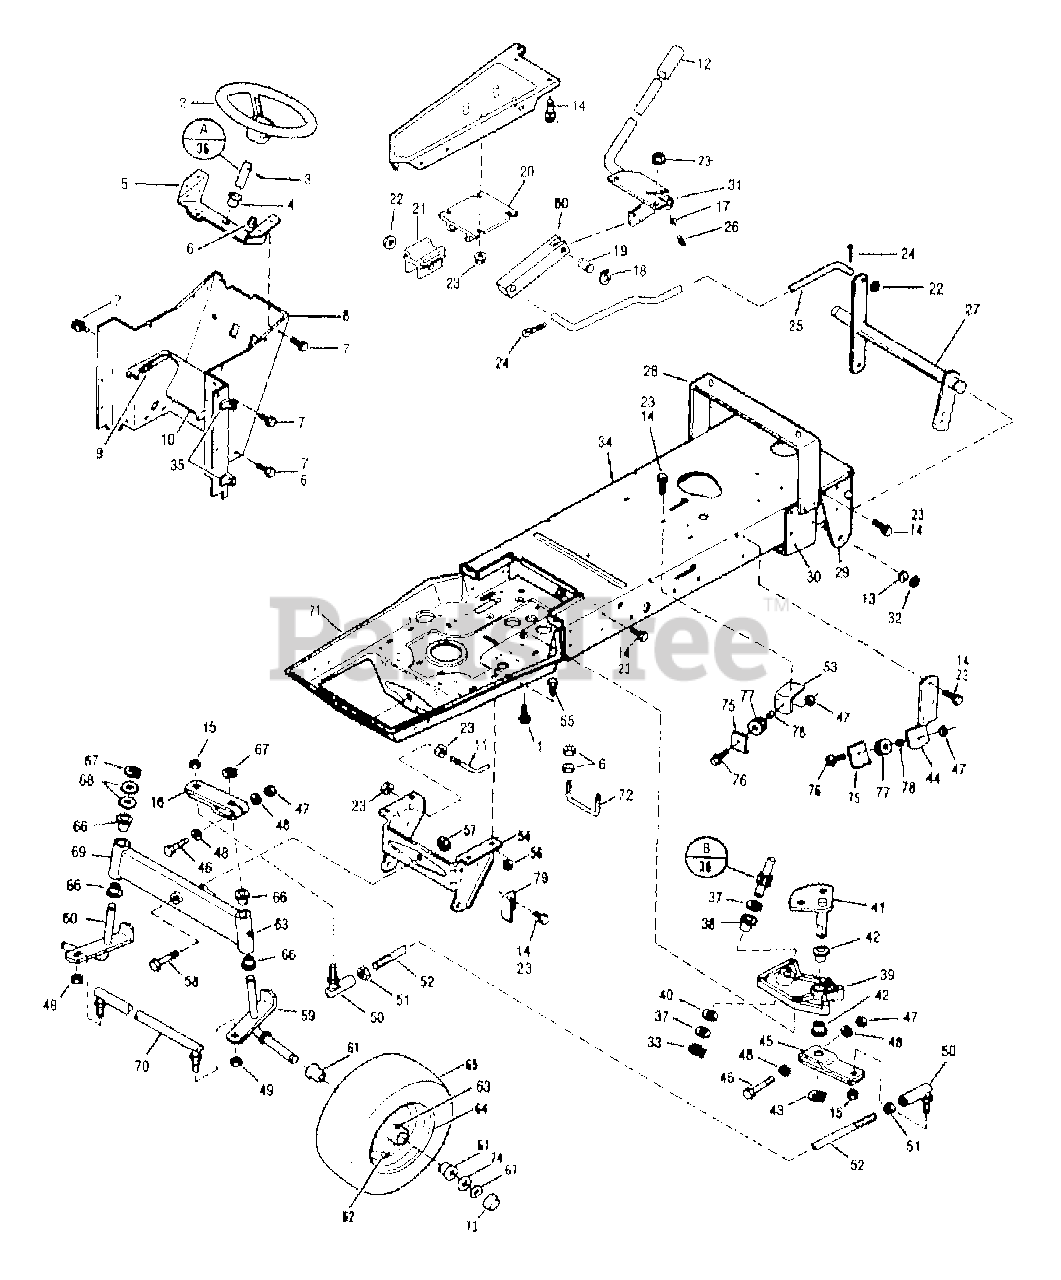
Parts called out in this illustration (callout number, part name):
1	SCR-HFLK 5/16-18X.75
2	WHEEL-STEERING
4	BEARING-FLANGED NYLON
5	SUPPORT-STEERING SHAFT
6	NUT-HF/LK 1/4-20 ZP
7	SCR-HH 1/4-20X.625 {7}
8	SUPT-INSTRUMENT PANEL
9	NUT-SPEED
10	SUPPORT-BATTERY
11	GUIDE-BELT
12	GRIP-FLEX
13	WASHER-1.38 X.765X .06 ZP
14	SCR-LOCK
15	NUT-HEX/JAM 1/2-20 ZP
16	ARM-STEERING
17	WASHER
18	RING-RETAINING
20	KIT-GUIDE (TRACTOR)
21	KIT-GUIDE (TRACTOR)
23	NUT-HFLK 5/16-18 ZP
25	ROD-LIFT
26	FITTING-GREASE
27	ASSM-LIFT SHAFT
28	ASSM-FENDER SUPPORT
29	ASSM-PANEL REAR
30	AXLE-SUPPORT
31	ASSM-LIFT LEVER
32	RING-RET."E".577 ID
33	RING-RETAINING
35	NUT-SPEED
36	SHIFT-STEER
37	WASHER-SHIM
38	BEARING
39	ASSM-STEER SUPT
40	WASHER-1.115X.637X.06
41	ASSM-SECTOR GEAR
42	BEARING-FLANGE
43	RING-RETAIN EXT .707 ID
44	BRACKET
45	ASSM-ARM SPINDLE
47	NUT-LOCK 3/8-16
48	WASHER-.875X.390X.134
49	NUT-LOCK
50	JOINT-BALL
51	NUT-JAM
52	ROD-STEERING
53	BRACKET
54	BRKT-ATTACHMENT
56	NUT-HFLK 3/8-16 ZP
57	NUT-H/LK 5/8-11
58	SCR-HH 5/8-11X2.25 G5 ZP
59	ASSM-SPINDLE LH
60	ASSM-SPINDLE RH
61	BUSHING
62	STEM-VALVE
63	FITTING-GREASE 1/4-28X2.00
64	WHEEL-RED
65	TIRE
66	BUSHING
67	RING-RET."E".577 ID
68	WASHER-1.25X.765X.049
69	ASSM-FRONT AXLE
70	ROD-TIE
71	FRAME-FRONT
72	GUIDE-BELT
73	CAP-WHEEL
74	WASHER-1.38 X.765X .06 ZP
75	GUIDE-CABLE
77	PULLEY-CABLE
78	SPACER-.75X.40X.51 P/M
79	BRACKET
